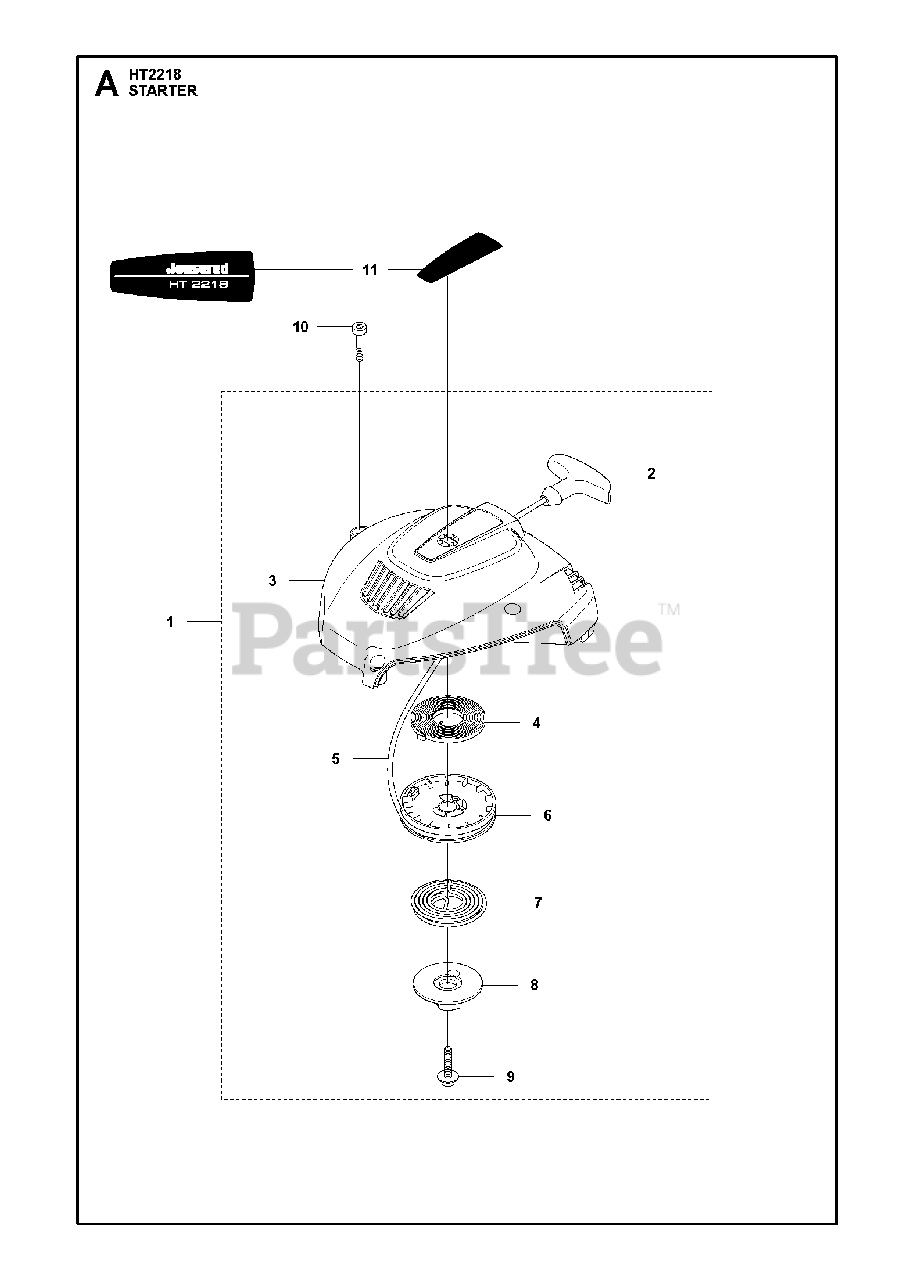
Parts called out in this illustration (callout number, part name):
4	SPRING
5	STARTER CORD
6	STARTER PULLEY
7	SPRING
8	DRIVER
9	SCREW
10	SCREW CITXSCMO M5X25
